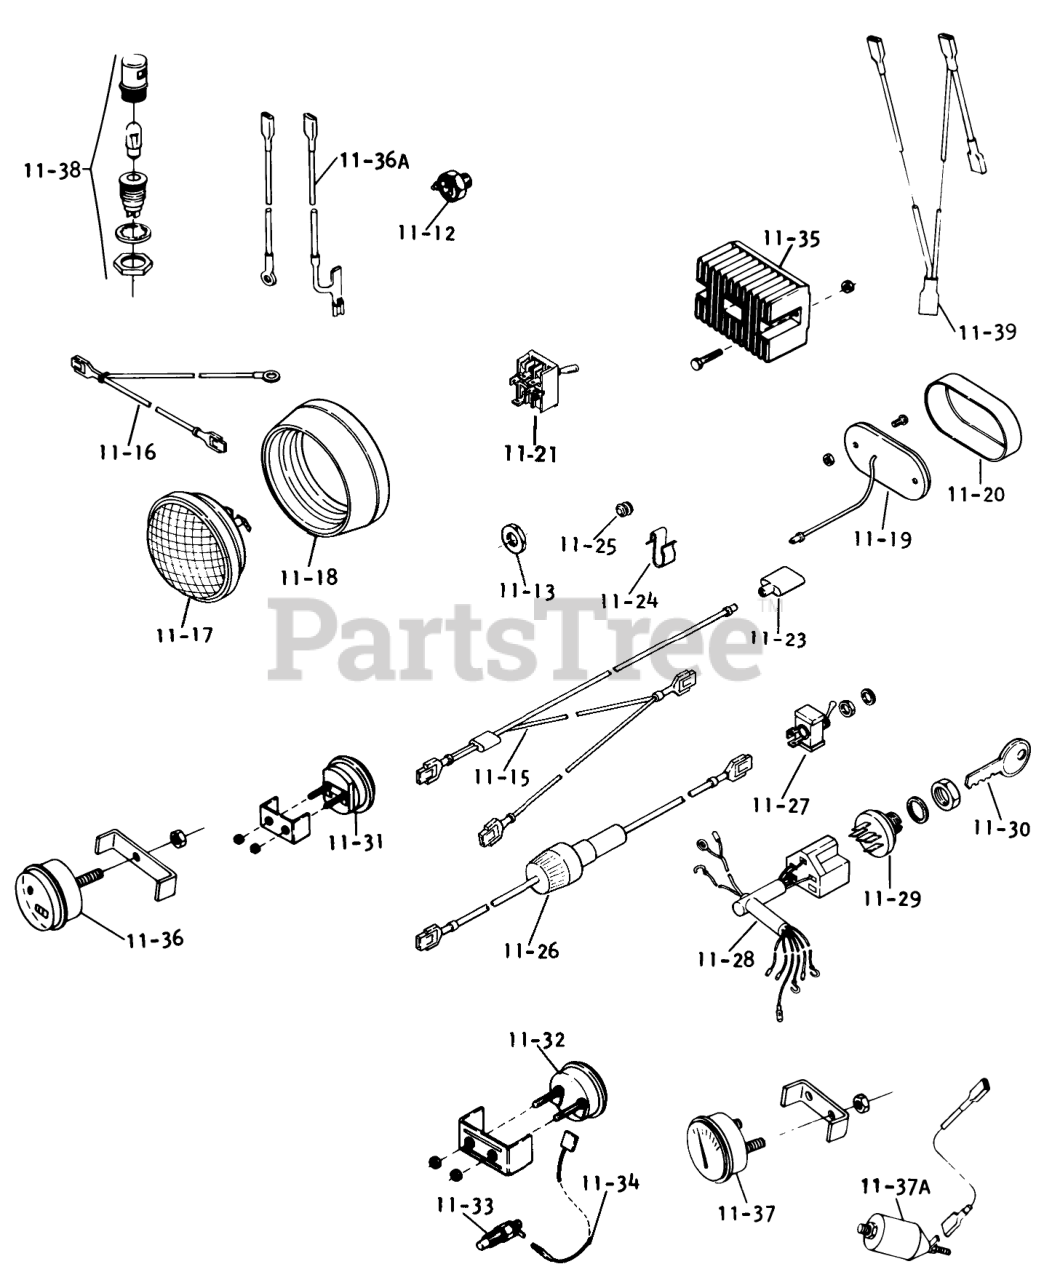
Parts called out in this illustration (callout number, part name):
11-01	Battery
11-02	Battery Box
11-03	Assy-Hold Down
11-04	Hook-Battery Retainer
11-05	ASSY-WIRE SOLENOID
11-06	ASSY-WIRE
11-08	Starter-Solenoid 20 1/2"
11-08	Cable
11-09	WIRE ASSY
11-10	Assy-Wire
11-11	Solenoid
11-11A	Bracket
11-12	SWITCH SAFETY
11-13	NUT-SPECIAL 9/16-18
11-15	Control Clip
11-16	Wire Assy
11-17	HEADLAMP
11-18	Grommet
11-19	BASE-TAIL LIGHT
11-20	Lens-Taillight
11-21	SWITCH CLUTCH
11-23	CONNECTOR 3 WIRE
11-24	SPEED CLIP
11-25	Grommet
11-26	ASSY FUSED CONNECTOR
11-27	SWITCH-LIGHTS
11-28	Wiring Harness
11-29	SWITCH-IGNITION
11-30	Key-EL
11-31	AMMETER W/CLAMP
11-32	Gauge-Oil Temp
11-33	Assy-Thermistor
11-34	Assy-Wre
11-35	REGULATOR-RECTIFIER
11-36	Clamp
11-36	Hour Meter
11-36A	Wire Assy
11-37	CLAMP MOUNTING
11-37	Gauge-Oil Pressure
11-37A	SENDER-OIL PRESSURE
11-38	SY WIRE HR METER G
11-38	LAMP-DASH
11-39	Assy-Wire Gauge
